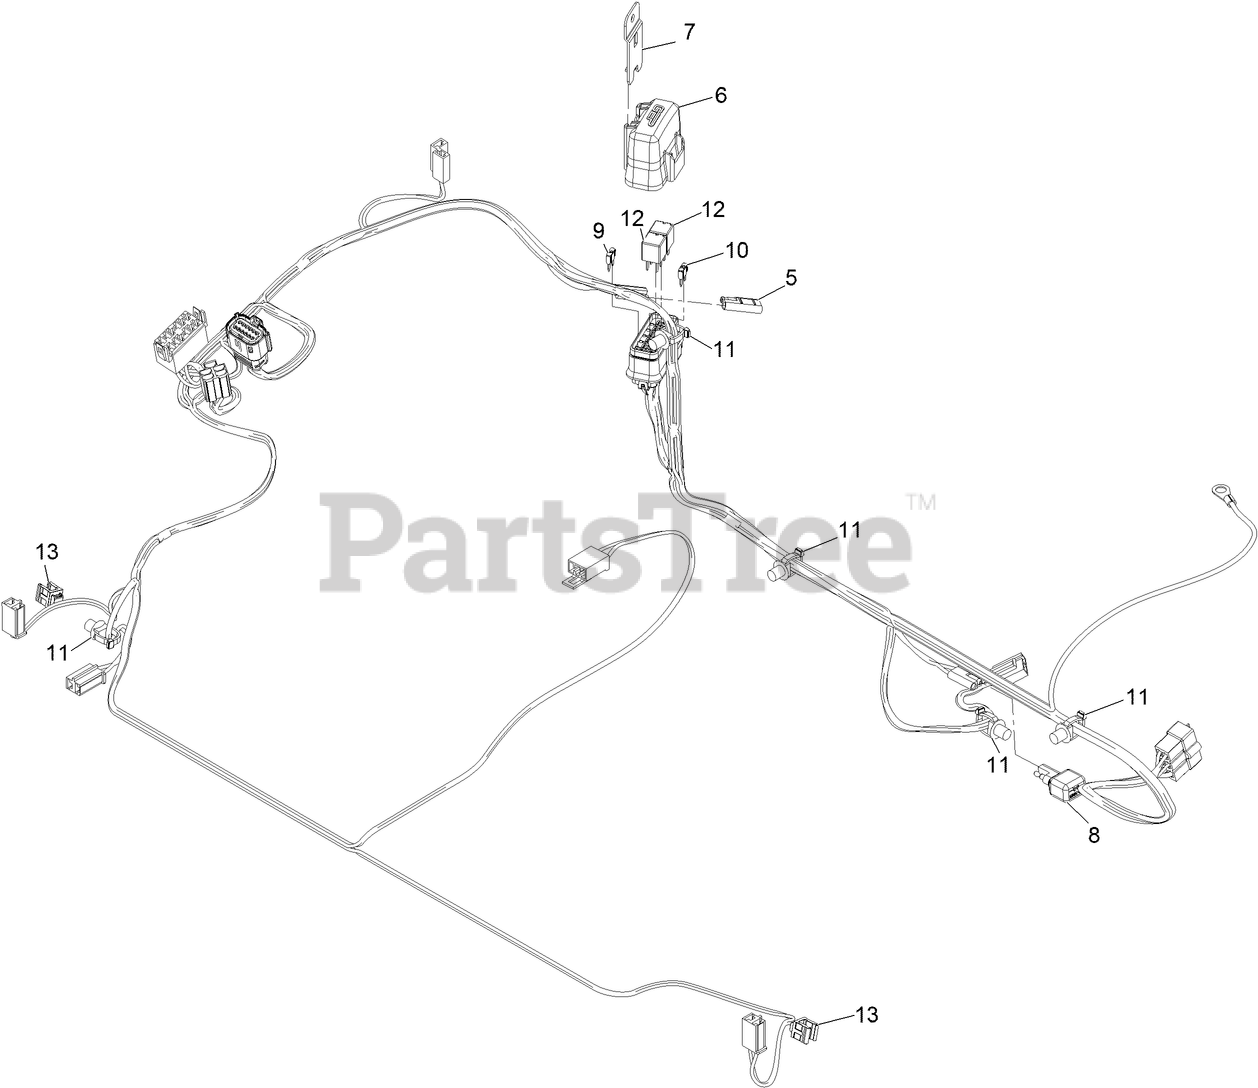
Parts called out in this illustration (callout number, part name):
5	CAP-PLUG
6	COVER-BLOCK, FUSE
7	CLIP-MOUNTING
9	FUSE-MINI BLADE, 15 AMP
10	FUSE-MINI BLADE, 20 AMP
11	CLIP-TIE
12	RELAY-MICRO
13	Clip-Edge
